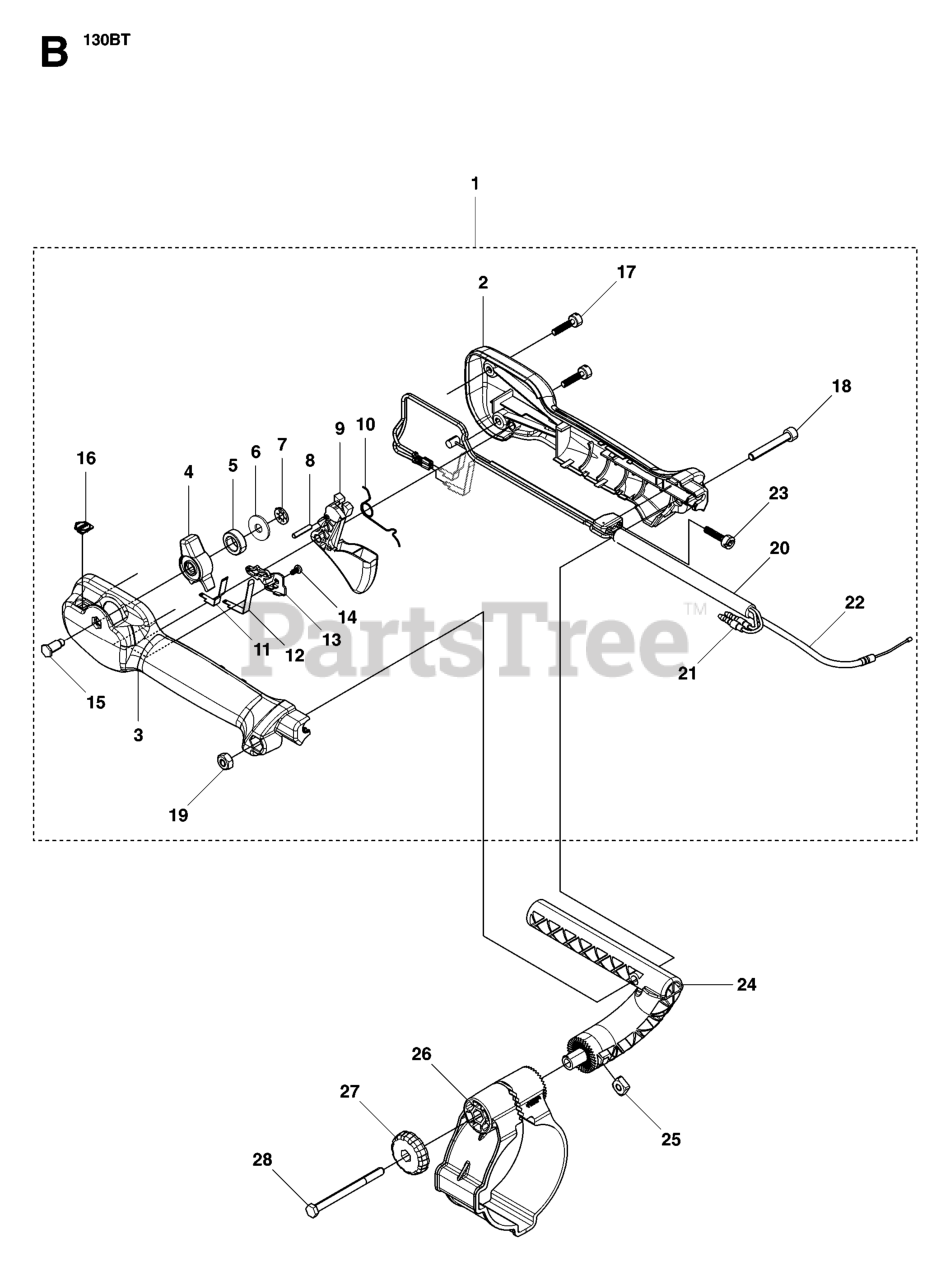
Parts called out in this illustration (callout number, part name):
1	LEVER
5	SPRING RUBBER
9	THROTTLE TRIGGER
11	CONTACT SPRING
12	CONTACT SPRING
18	SCREW
24	BRACKET
26	HOLDER TH
